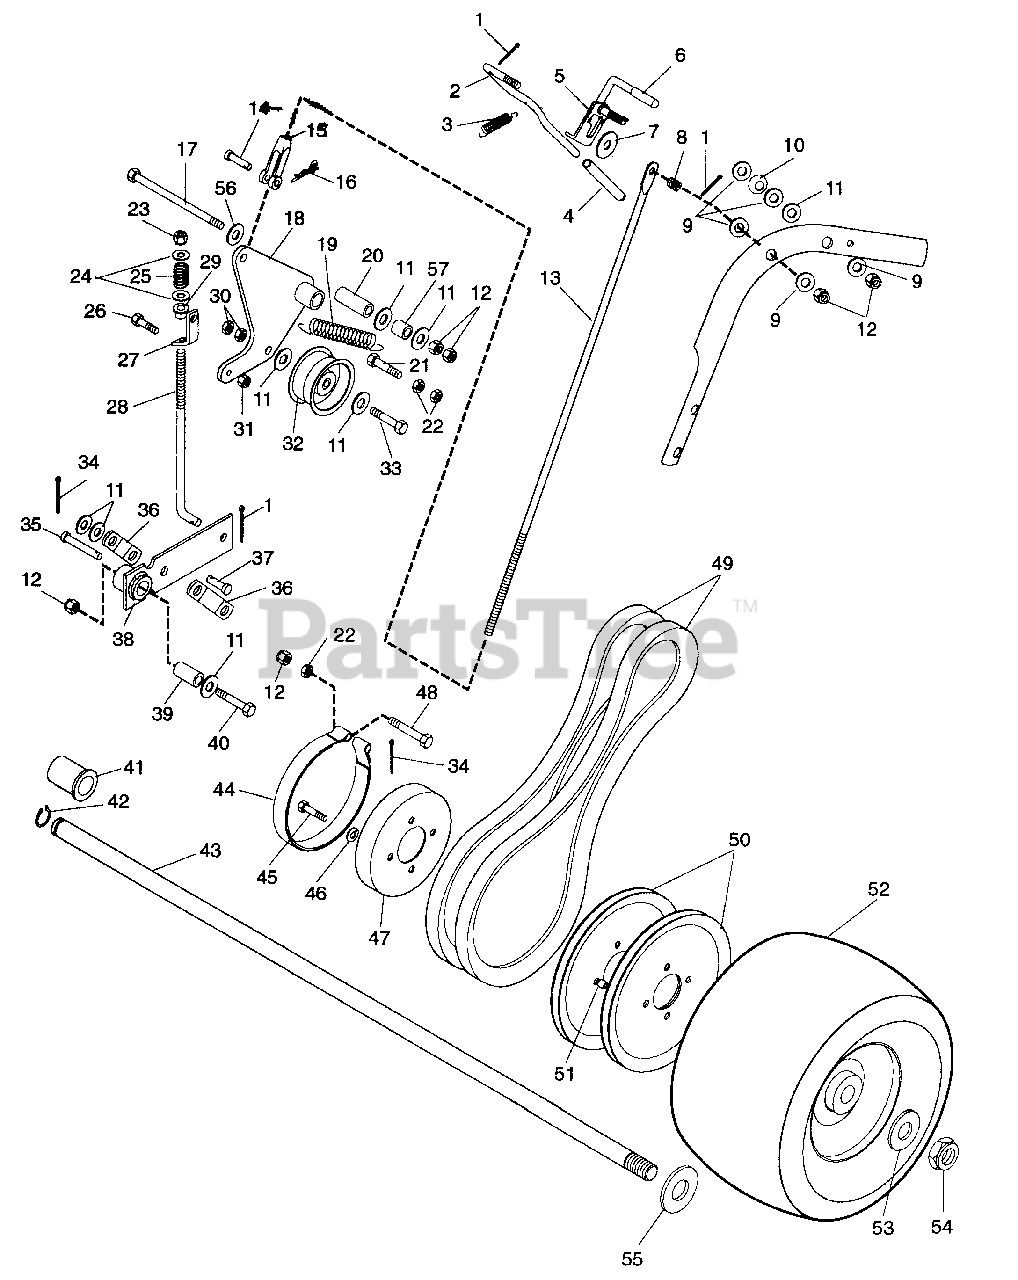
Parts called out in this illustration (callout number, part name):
1	Pin-Cotter .09 x .75
2	Lever, Hand Control
3	Spring-Tension .041 x .500 x 1.750
4	Grip, Hand Clutch Lever
5	Weldment, Clutch-Brake Lock
6	Tip-Brake Lock Lever
7	Washer-Flat-Steel .438x 1.375 x .083
8	Spring-Compression .045 x .600 x .750
9	Washer-Flat-Nylon .375 x .75 x .060
10	Spring Washer
11	Washer-Flat-Steel .406 x .812 x .065
12	Nut-Locking-Nylon .375-16 Grade 2
13	Rod, Clutch Actuating
14	Pin-Clevis .372 x 1.25
15	Clevis, .38-24 Adjustable
16	Pin-Hair Internal .08 x .18 x 1.18
17	Bolt-Hex .38-16 x 4.00
18	Weldment, Wheel ClutchArm
19	Spring-Tension .069 x .62 x 3.50
20	Bushing, Sleeve .385 x .610 x 1.80
21	Bolt-Hex .38-16 x 1.50 Grade 5
22	Nut-Hex .375-16 Grade 2
23	Nut-Locking-Nylon .312-18 Grade 2
24	Washer-Flat-Steel .344 x .688 x .065
25	Spring-Compression .125 x .78 x 1.00
26	Bolt-Hex .25-20 x .75 Grade 5
27	Left-Bracket, Pro Brake Link
28	Rod, Brake
29	Bushing-Flange .320 x .620 x .312
30	Nut-Locking-Center .625-10 Grade 2
31	Nut-Locking-Nylon .250-20 Grade 2
32	Sheave 3.25 x 1.25
33	Bolt-Hex .38-16 x 2.25 Grade 5
34	Pin-Cotter .12 x .75
35	Pin Clevis .372 x 1.25
36	Link, Brake Arm
37	Pin-Clevis .38 x .594
38	Weldment, Brake Arm
39	Bushing, Sleeve .391 x .622 x .950
40	Bolt-Hex .38-16 x 2.00 Grade 5
41	Bushing-Flange 1.010 x 1.38 x 1.4 x 1.65
42	Ring-Retaining-External .906 x .078
43	Axle Shaft, Pro-150
44	Assembly, Brake Band, Pro
45	Bolt-Hex .31-18 x 1.50 Grade 5
46	Washer-Lock .313 x .078
47	Drum, Brake
48	Bolt-Hex .38-16 x 2.00 Grade 5
49	Drive Belt, Pro 100, Matched Pair
50	Pulley-V 9.00 x 3.75
51	Bushing, Sleeve .385x .625 x .475
52	Assembly, Wheel, 13 x 6.00-6
53	Washer-Hardened-Thrust 1.002 x 1.552 x .030
54	Nut-Locking-Jam-Nylon.75-1.0
55	Washer-Thrust 1.55 x 1.002 x .093
56	Washer-Flat-Steel .390 x .875 x .18
57	Bushing
